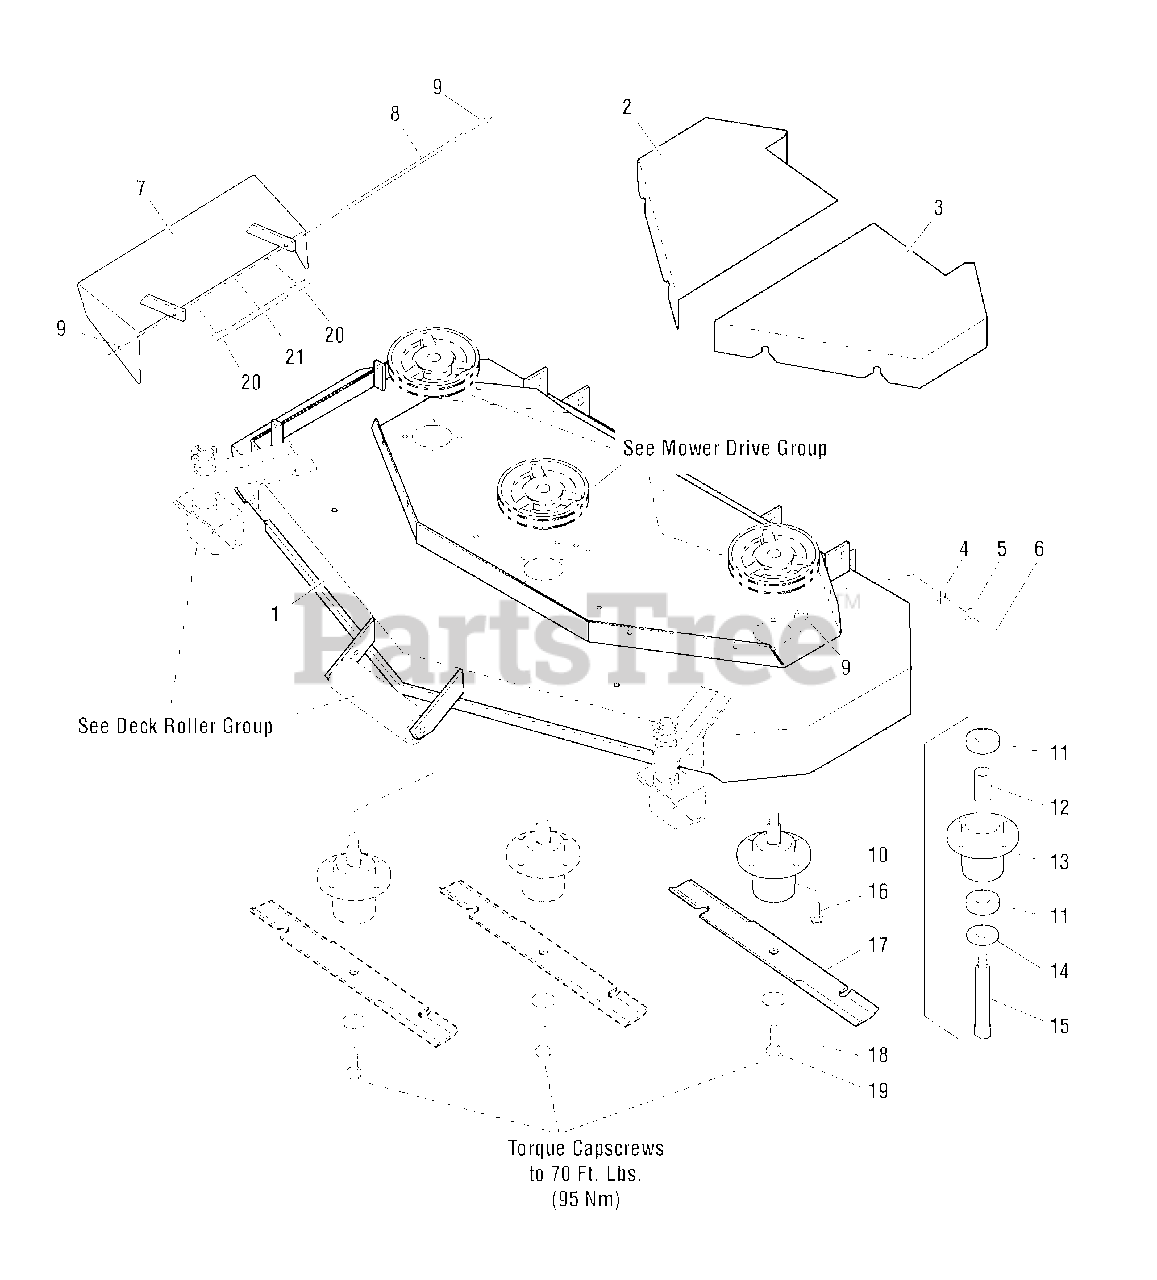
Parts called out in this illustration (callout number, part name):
1	MOWER HOUSING, 61"
2	SPINDLE COVER-RH
3	SPINDLE COVER-LH
4	BODY CLIP, 5/16-18
5	WASHER, 5/16
6	CAPSCREW, Hex Hd, 5/16-18 x 3/4
7	DISCHARGE CHUTE
9	NUT, Hex, Nylon Lock, 5/16-18
11	BEARING, Ball
12	SPACER, Bearing
13	SPINDLE HOUSING
14	TRASH SHIELD
15	SPINDLE SHAFT
16	CAPSCREW, Hex Flange Head, 5/16-18 x 1-1/4
17	MOWER BLADE
18	WASHER, USS, 5/8
19	CAPSCREW, Hex Hd, 5/8-11 x 1-3/4
20	SPRING, Torsion
21	SPRING SPACER
